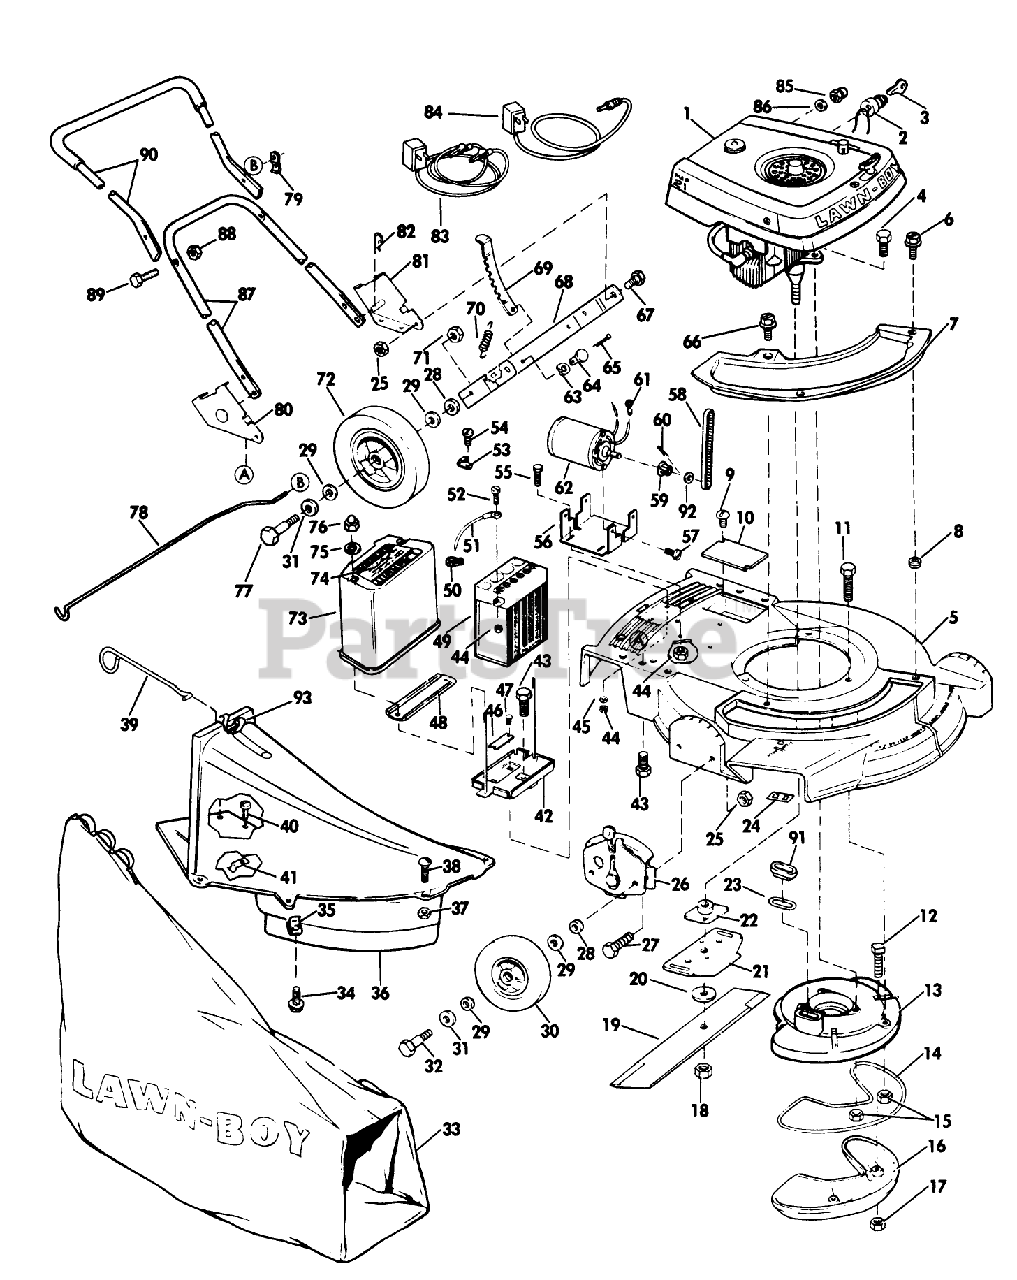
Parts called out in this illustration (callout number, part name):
6	SCREW SEMS TRM HEX HD
11	SCREW
15	NUT
17	LOCKNUT E
18	NUT-BLADE
20	WASHER
22	PLATE AND COLLAR ASM
23	GASKET S
25	NUT
28	WASHER WROUGHT
29	WASHER
31	SPACER
32	BOLT WHEEL
33	89802 LB WHOLE GOODS
34	SCREW
35	SPEED NUT ARDEN
36	Skirt Assembly
37	NUT S
45	Washer
50	RETAINER ARDEN
51	Lead Assembly
52	SCREW F
54	SCREW S
55	SCREW S
63	WASHER SPRING LAR
64	PIN
70	SPRING N.A.S
71	LOCKNUT
75	Washer
76	PALNUT S
77	BOLT
78	ROD & CLIP
82	HAIR PIN
84	BATTERY CHARGER
89	SCREW
91	SLEEVE
